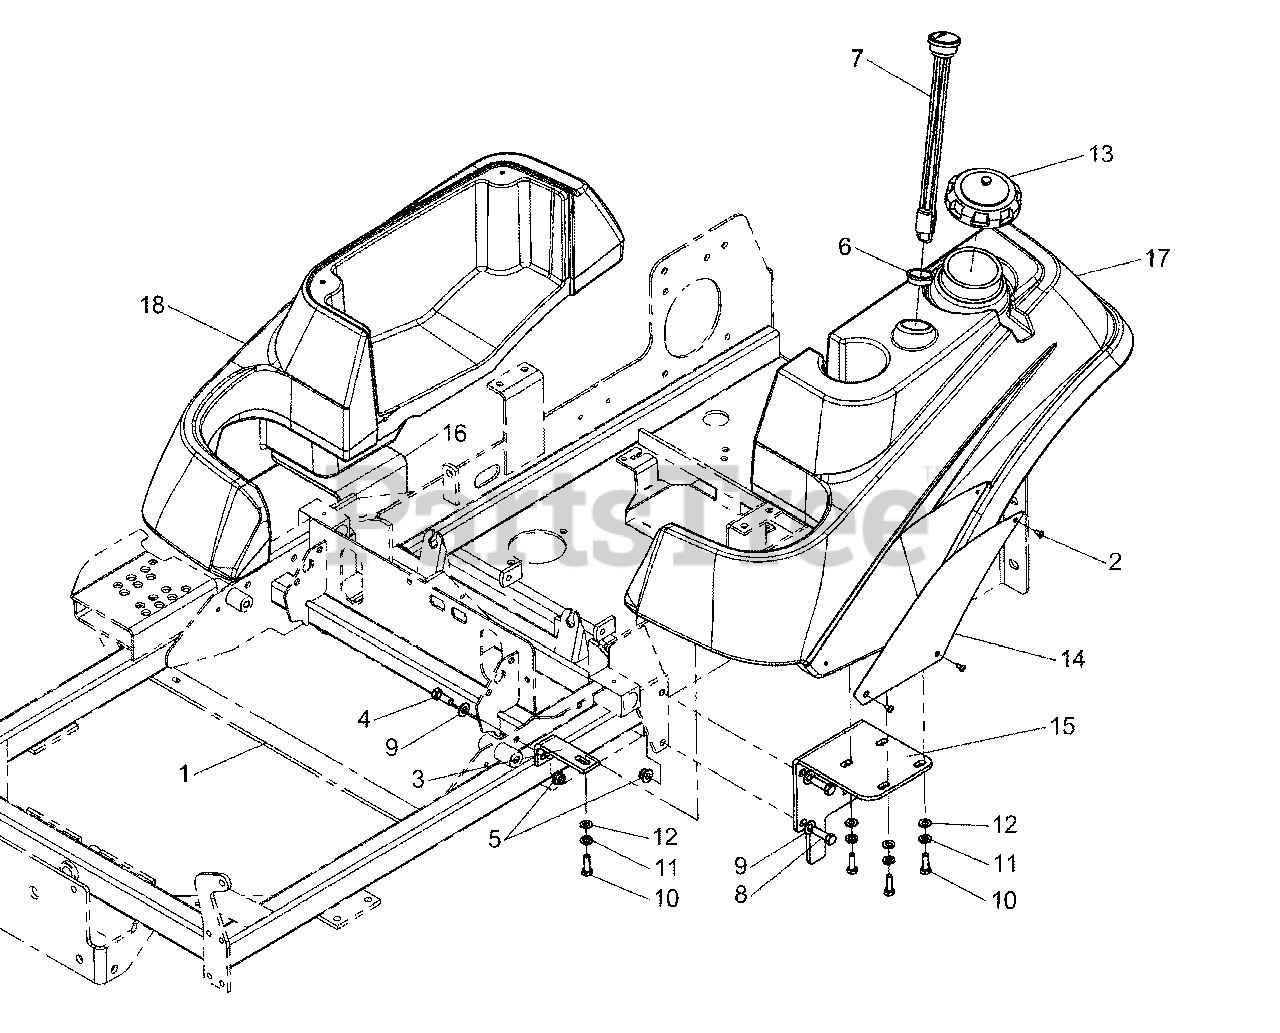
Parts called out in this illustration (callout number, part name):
1	MAIN FRAME
2	SCREW, Allen Head, #10-24 x 3/8"
3	MOUNT, TANK, FRONT - BLK
4	BOLT, 3/8-16 X 1" GD5
5	NUT, 3/8-16 Hex Nylock Flange
6	GROMMET
7	GAUGE, FUEL LEVEL
8	BOLT, 3/8-16 X 1-1/4"
9	WASHER 3/8" GD.9 FLAT
10	BOLT, 5/16-18 X 1"
11	WASHER, 5/16" Lock
12	WASHER, 5/16" GD.9 FLAT
13	FUEL CAP, 3-1/2", MANAGED VENT OUT, 12"
13	FUEL TANK CAP
14	PLATE, BADGE
15	TANK MOUNT - LH
16	TANK MOUNT - RH
17	TANK, FUEL, LH, 1500Z
17	TANK, FUEL, CITATION/ZT400 - LH
18	TANK, FENDER, CITATION/ZT4000 - RH
